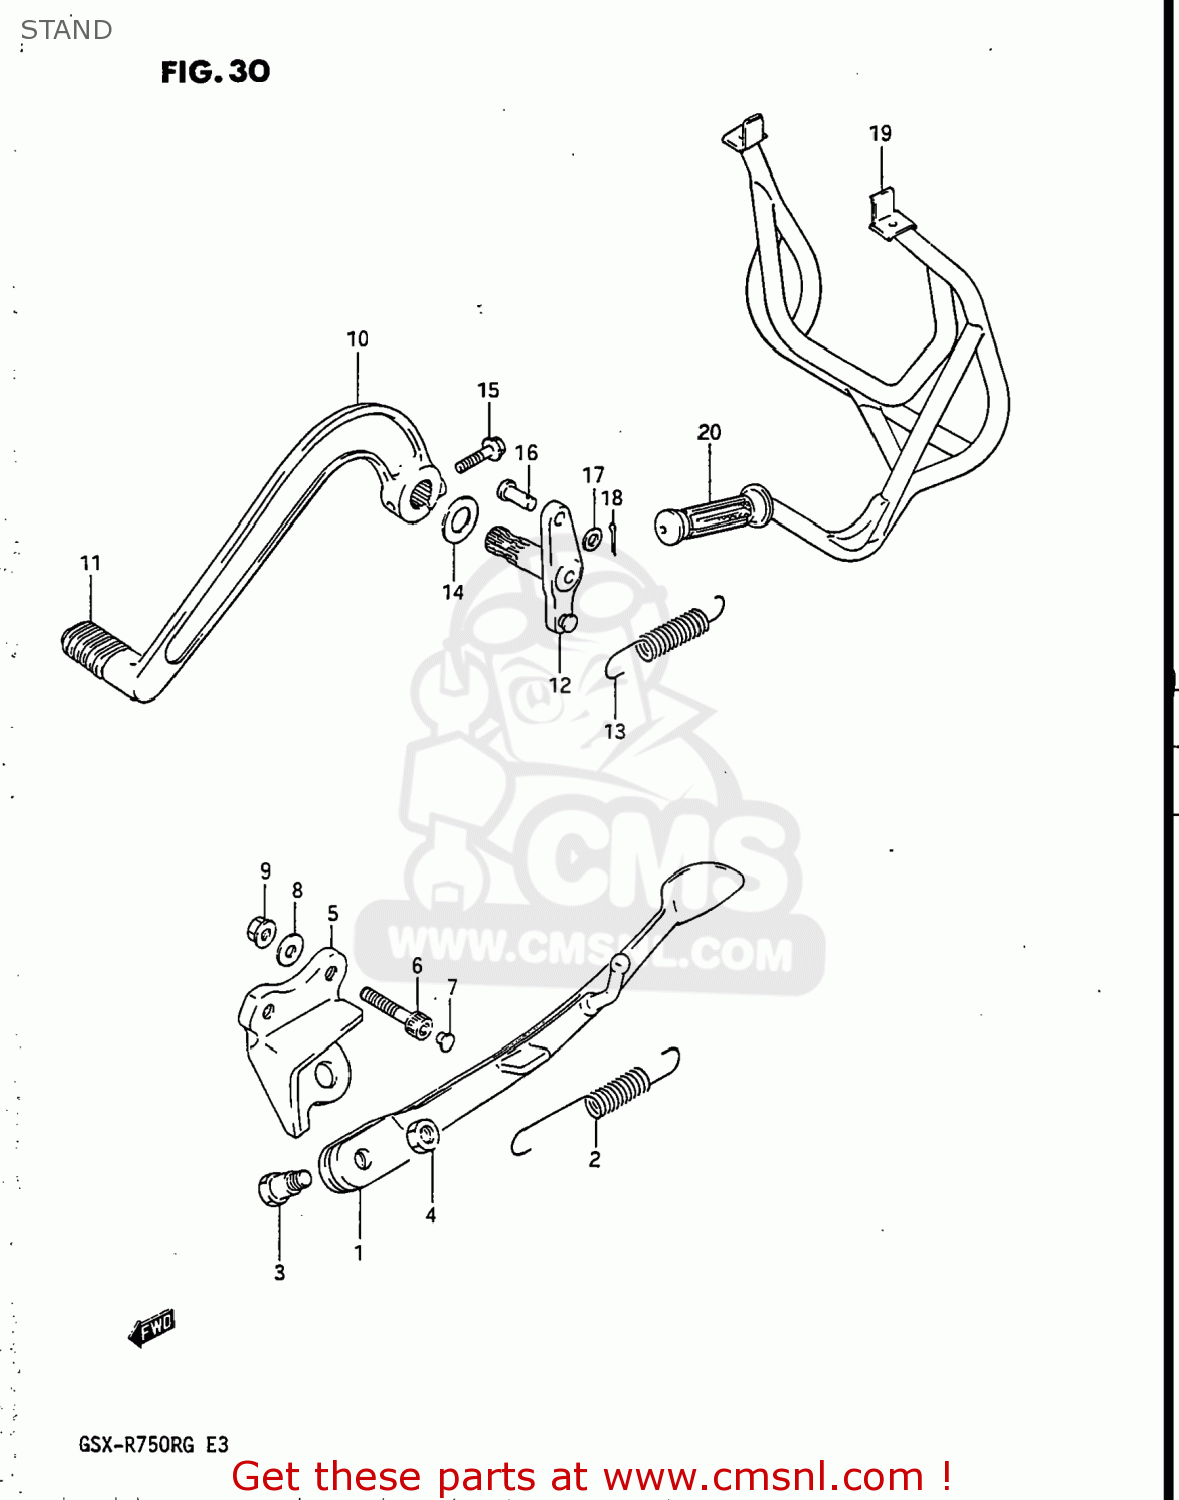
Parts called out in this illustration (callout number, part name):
1	STAND,SIDE
2	SPRING
3	BOLT(10X38)
4	NUT
5	BRACKET,SIDE STAND
6	BOLT, FRONT RH
7	CAP,ENGINE MOUNTING
8	WASHER
9	NUT
10	PEDAL,BRAKE
11	RUBBER,BRAKE PEDAL
12	ARM COMP,BRAKE ROD
13	SPRING
14	WASHER,BRAKE PEDAL
15	BOLT
16	PIN
17	WASHER
18	PIN
19	STAND,CENTER
20	GRIP,L
